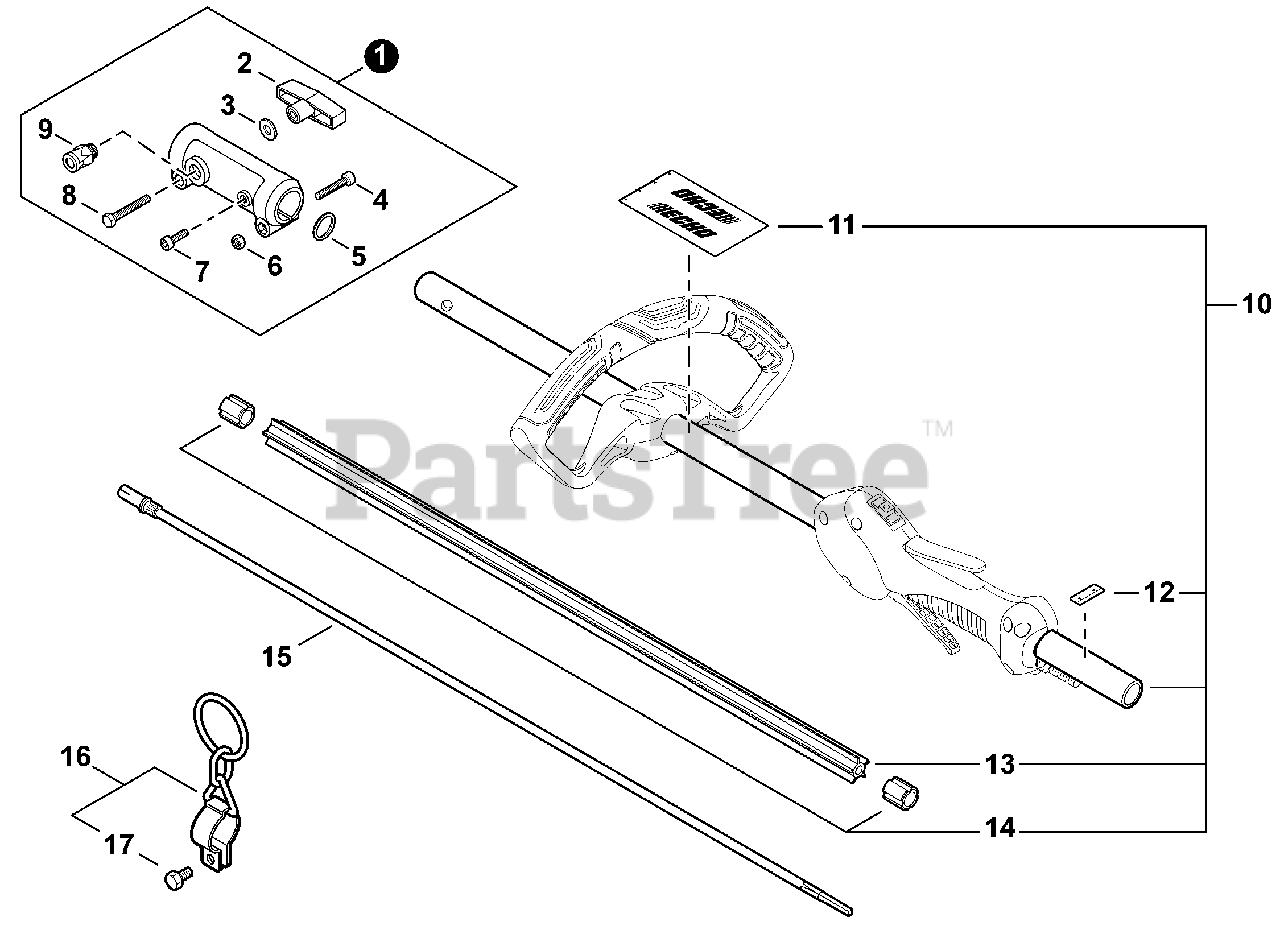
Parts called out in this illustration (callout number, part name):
1	COUPLER ASSY
2	KNOB, FASTENER
3	WASHER 6.6×20×1.6
4	BOLT, TORX 6×25
5	WASHER 18 SPR STEEL
7	BOLT, TORX 5×10
8	BOLT 6×40
9	LATCH ASSY
10	MAIN PIPE ASSY
11	LABEL, HANDLE LOCATION
12	LABEL - ALIGNMENT
13	LINER - FLEXIBLE
15	DRIVESHAFT - FLEXIBLE
16	HANGER SET, HARNESS
17	BOLT 5×12
